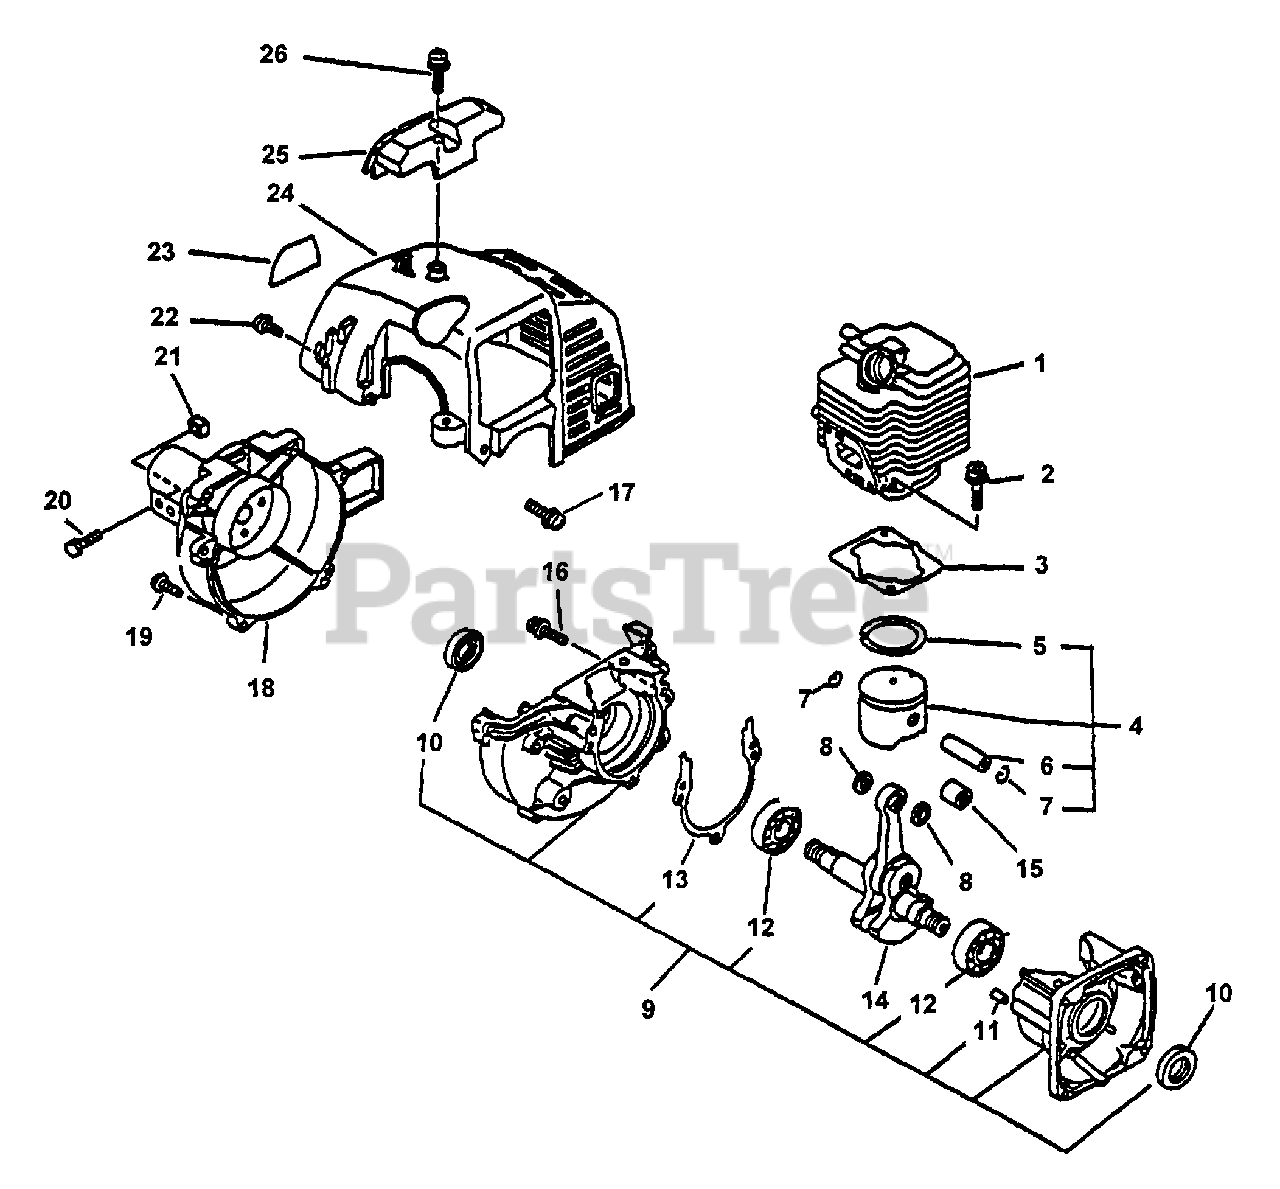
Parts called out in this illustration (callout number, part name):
1	CYLINDER
2	SCREW - 5X22
3	GASKET, CYLINDER
4	PISTON KIT
5	RING, PISTON
6	PIN, PISTON
7	RING, RETAINING
8	SPACER, PISTON
9	CRANKCASE KIT
10	SEAL, OIL
11	PIN - LOCATING
12	BEARING, BALL - 6201
13	GASKET, CRANKCASE
14	CRANKSHAFT ASSY
15	BEARING, NEEDLE
16	SCREW - 5X28
17	SCREW - 4X12 -- TAPPING
18	FAN CASE ASSY
19	SCREW - 4X18
20	BOLT - 5X28
21	NUT - 5 -- SQUARE
22	SCREW - 4X16
23	LABEL - MODEL PE-2000
24	COVER, ENGINE - GRAY
25	GUARD, TOP - GRAY
26	SCREW - 5X16 -- TAPPING
